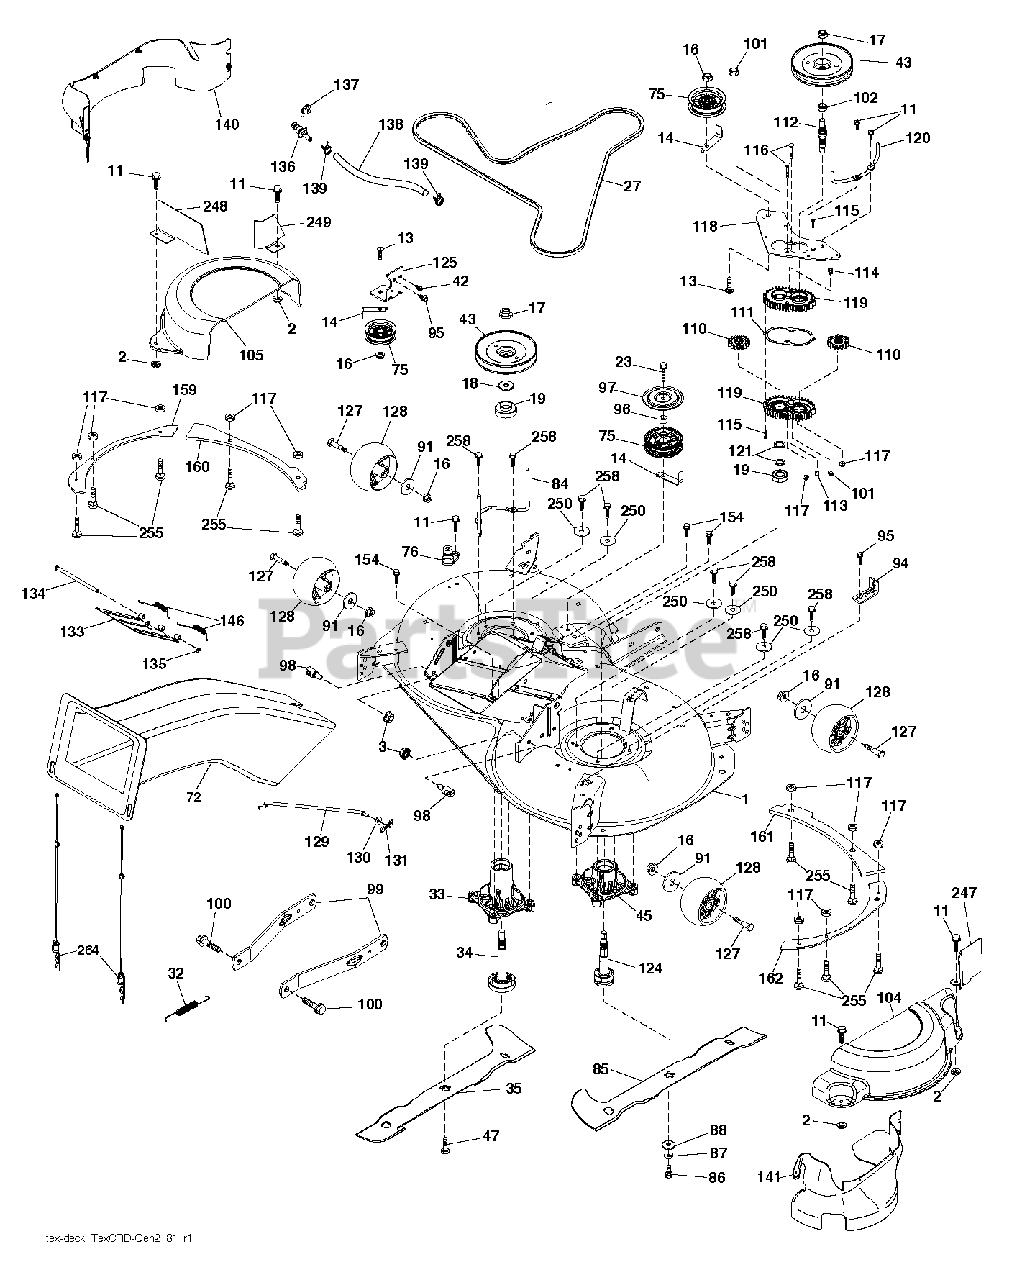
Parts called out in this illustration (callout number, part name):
1	DECK SVC 107HP.EZMUL.498
2	PALNUT 1/4
3	NUT LOCK HEX FLANGE 5/16-18
11	SCREW.1/4-20X5/8
13	BOLT.3/8-16X1.50
14	KEEPER, BELT IDLER
16	NUT LOCK FLG 3/8-16 UNC
17	NUT.FLANGE.LOCK.TOP
18	WASHER.SPACER.MANDREL
19	BEARING.MANDREL.TOP.EXTENDED
23	SCREW LT
27	BELT.ELECT.MOWER.DRIVE 97.8 EL
32	SPRING 107CM & 97CM ELECTRIC D
33	HOUSING.MANDREL.REV.TALL.N/GRS
34	SHAFT ASM.REV.TALL.N/GREASEBL
35	BLADE.107.LH.SINGLE.NON.QD
42	SCREW
43	PULLEY PULLEY MANDREL 5.438 PD
45	RP HOUSING.MANDREL.REV.REVS.
47	SCREW.SEMS.7/16-20X1.HEX.HEAD
72	RB CHUTE 107/97 TEX GENII
75	FLAT IDLER PULLEY
76	1/2" BARB.DECK.WASHOUT.PORT
84	KEEPER KEEPER. LH MANDREL BELT
85	BLADE.107.RH.SINGLE.NON.QD
86	BOLT.3/8-24X1.25GR8. LHTHRD
87	LOCKWASHER
88	WASHER.BLADE
91	WASHER
94	BRKT.CLUTCH.CABLE
95	SCREW, 3/8-16X3/4
96	SPACER
97	PROTECTOR
98	STUD.FASTNER.W/ANTI-ROTATE
99	ARM.SUSPENSION.MOWER.R
100	BOLT.SHOULDER
101	NUT.CROWNLOCK.9/16 -18.UNC
102	SPACER BEARING
104	COVER.MANDREL.107.RH.GEN.2
105	COVER.MANDREL.107.LH.GEN.2
110	CRD.SPUR.GEAR
111	GASKET GASKET GEARCASE
112	SHAFT SHAFT. CRD GEARCASE ADAP
113	PLUG PLUG OIL
114	VENT.BREATHER.1/8 NPT
115	SCREW
116	BOLT.CARIGE.SS.1/4-20X1.75GR5
117	NUT T
118	ARM ARM. CLUTCHING 107 TEX CRD
119	GEARCASE GEARCASE SUBASM
120	KEEPER KEEPER. RH MANDREL BELT
121	WASHER WASHER
124	SUB.ASM.REVERSE.THREAD.REV
125	BRACKET BRACKET IDLER CHASSES
127	BOLT.SHOULDER.3/8-16X3-5/8.
128	WHEEL. GUAGE RALLY
129	ROD ROD. SWAY CRD GEN II
130	WASHER
131	PIN.COTTER.5/16.BOW TI
133	COVER DOOR.107 CM CRD EZ MULCH
134	PIN PIN.HINGE
135	E-RING.5/16"
136	PLUG WASHOUT PORT HOOKUP
138	107.WASHOUT.PORT.HOSE (2 2)
139	HOSE.3/8.CLAMP (2 2)
140	GUARD.ASSEMBLY.107.LH.FRENCH
141	GUARD.ASSEMBLY.107.RH.FRENCH
146	SPRING SPRING: EZ MULCH DOOR
154	SCREW T-30 1/4-20 X
159	REINFORCE.PLATE.LH.FT.X431
160	REINFORCE.PLATE.LHS.BOLT.431
161	REINFORCE.PLATE.RH.FRT.X431
162	REINFORCE.PLAT.RH.SD.BLT.X431
247	GUARD.STEEL.CRD.MANDREL.COV.FR
248	GUARD.STEEL.CRD.MANDREL.COV.FR
249	GUARD.STEEL.CRD.MANDREL.COV.FR
255	RHSNB, 1/4-20 X 1, GR5
258	BOLT.HEX.WASHR.HED.313-18X1.19
264	RETAINER.ASM.UPPERCHU
